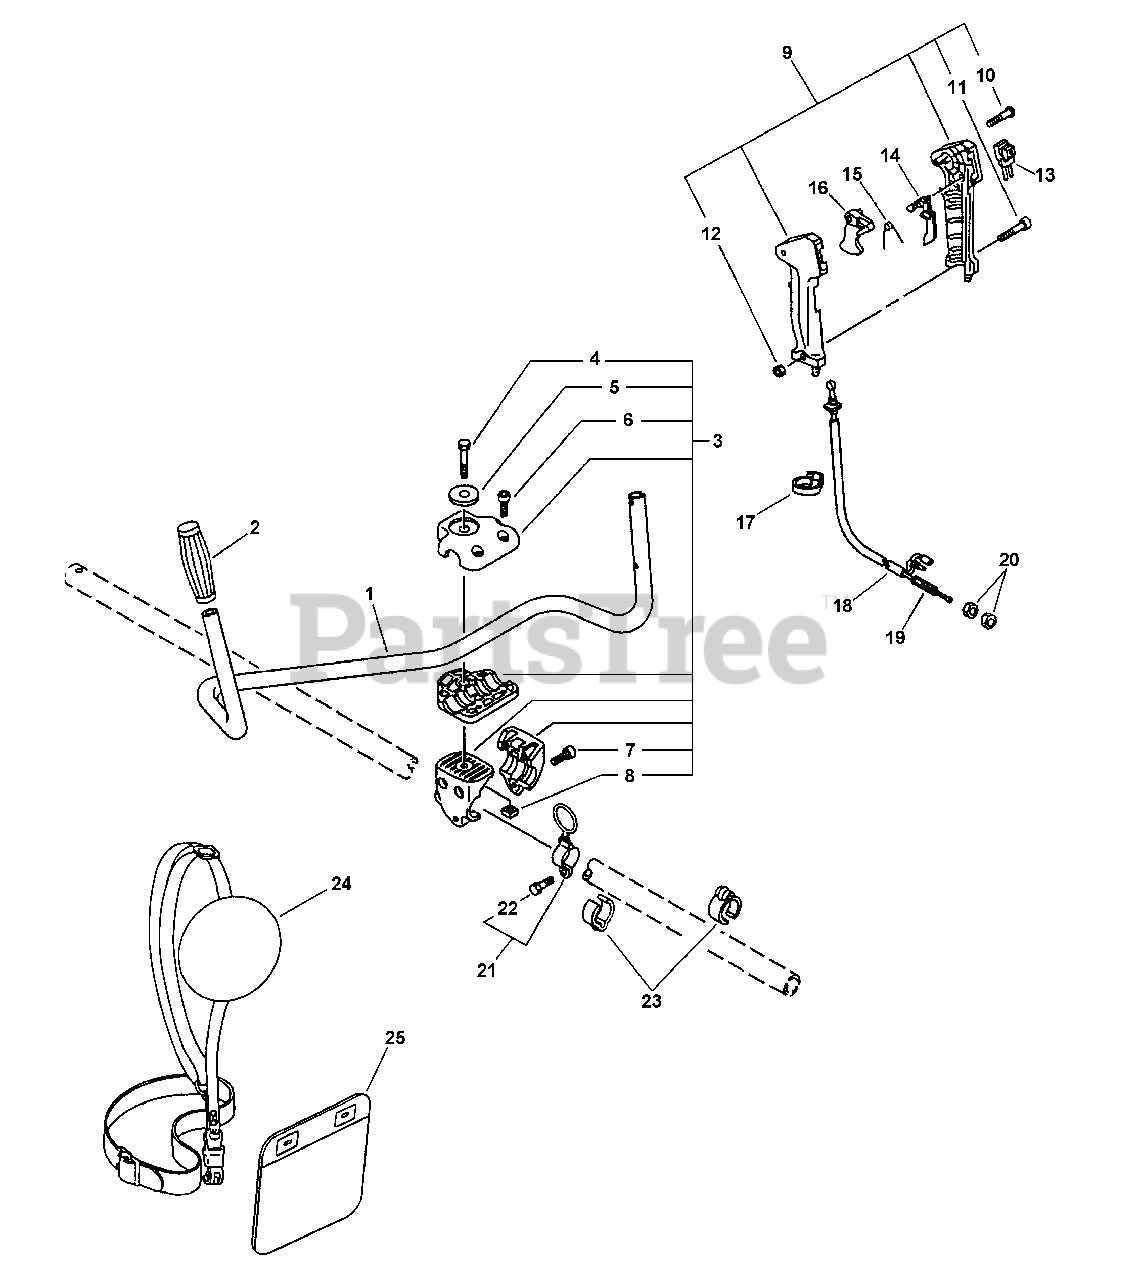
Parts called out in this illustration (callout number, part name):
1	Handle, Front
2	Grip, Handle
3	Handle Bracket Asy
6	Bolt 5x20
7	Bolt 5x30
9	Front Handle Grip Asy
10	Screw 3x25
11	Screw 5x30
13	Switch, Ignition
14	Lockout, Throttle
15	Spring, Throttle Lock
16	Control, Throttle
17	Clip
19	Cable, Throttle
21	Hook Ring Asy
22	Bolt 5x12
24	Harness, Shoulder
25	Cushion
